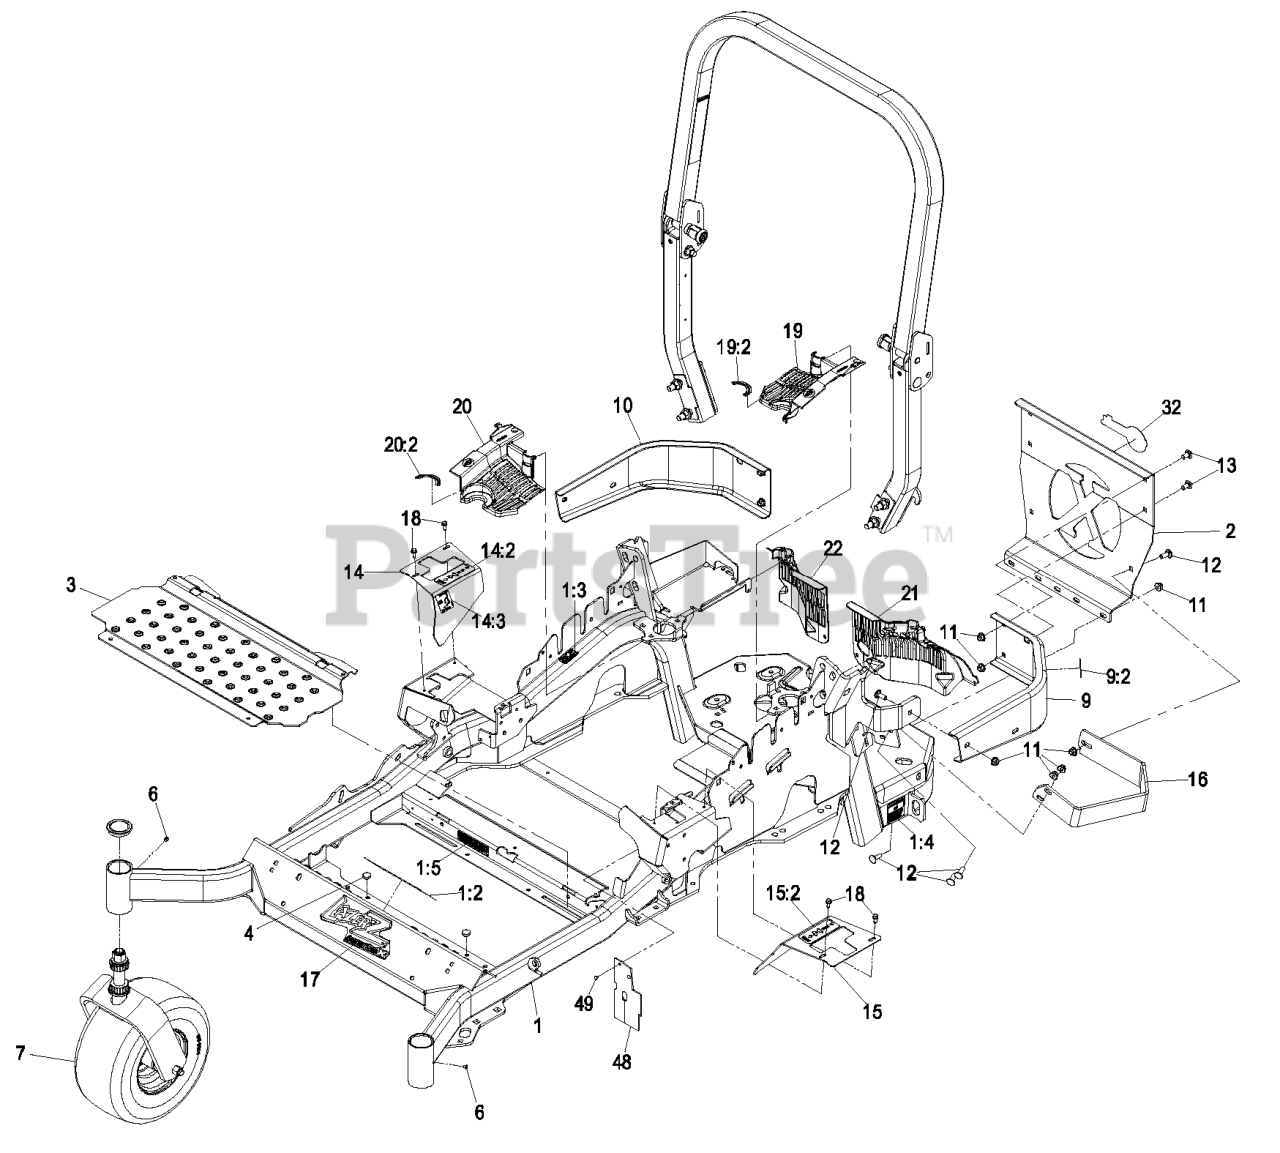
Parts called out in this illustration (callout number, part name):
1	MAIN FRAME ASM
1:2	DECAL-WARNING
1:3	DECAL-CAUTION
1:4	DECAL-BELT DRIVE
1:5	DECAL-ARRESTER, SPARK
2	PLATE,REAR GUARD
9	LH BUMPER ASM
9:2	DECAL-CAUTION
10	BUMPER-RH
11	NUT-HF, NI
12	SCREW-CARR
13	SCREW-CARR
14:2	DECAL-MOTION CONTROL
15	LH MOTION CONTROL COVER ASM
15:2	DECAL-MOTION CONTROL
17	DECAL,LAZER ASX LOGO
18	SCREW-HWH
19	LH HYDRO GUARD ASM
19:2	DECAL-HYDRO OIL
20	RH HYDRO GUARD ASM
20:2	DECAL-HYDRO OIL
21	GUARD-HYDRO, REAR (LH)
22	GUARD-HYDRO, REAR (RH)
39	ASM,AIR DEFLECTOR
40	SCREW-HH
41	WASHER-SPRING
42	NUT-HF, NI
48	DEFLECTOR-AIR FLOW
49	RIVET-POP
